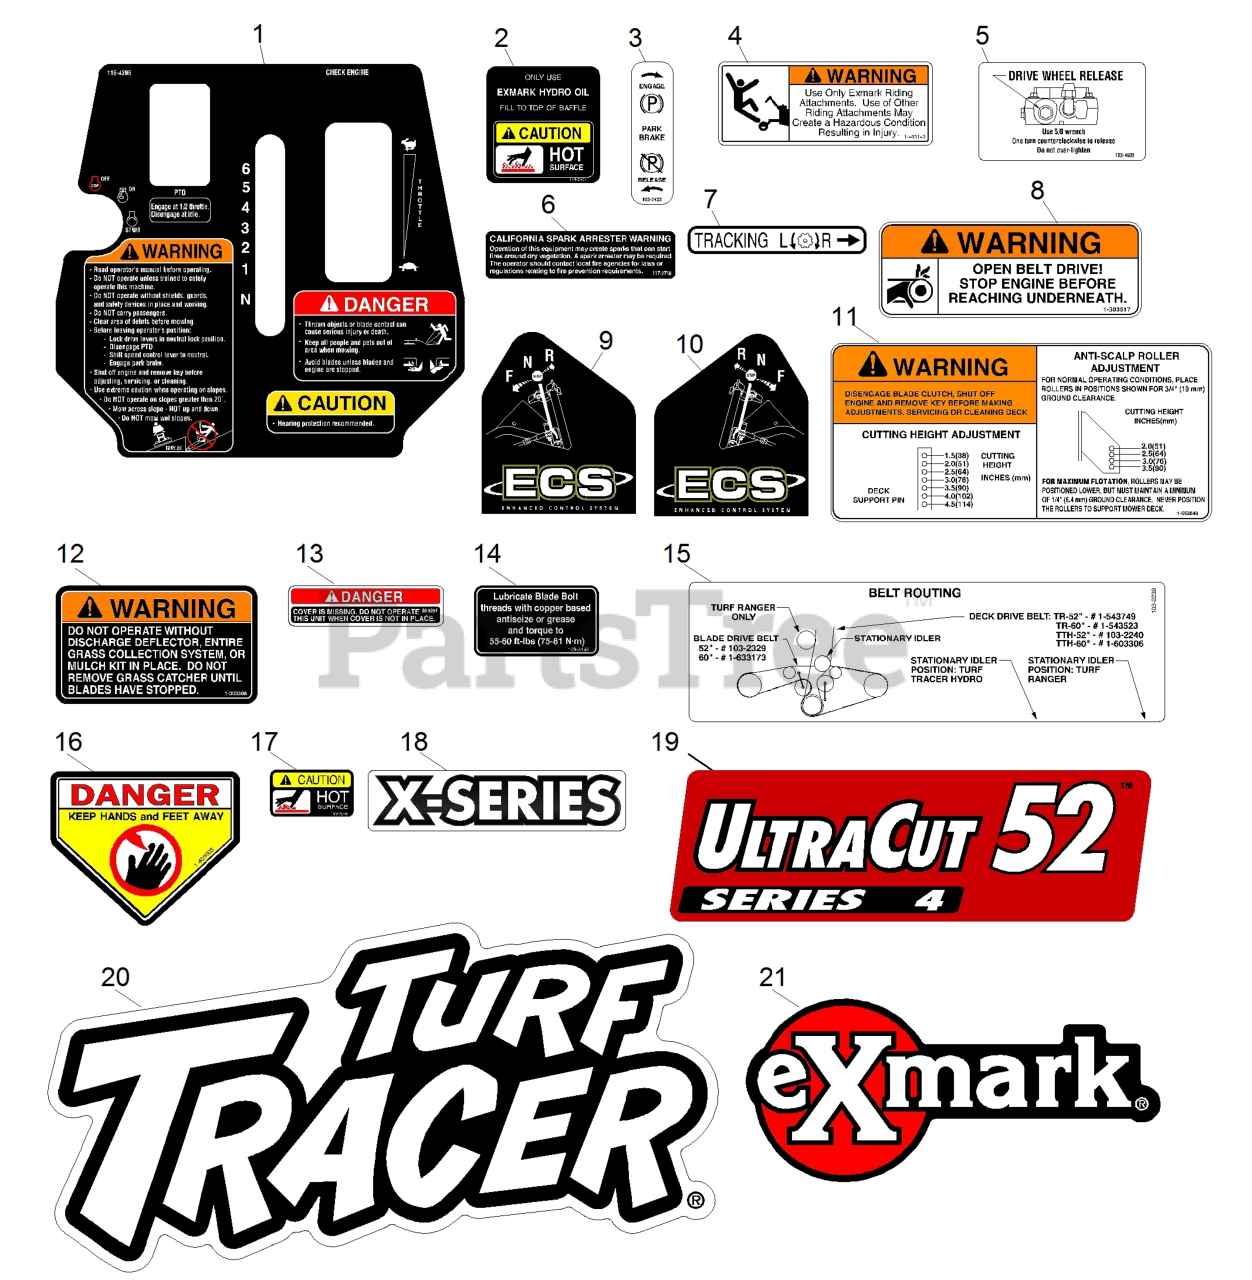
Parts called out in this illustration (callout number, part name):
1	DECAL,CONSOLE TTX
2	DECAL-HYDRAULIC TANK
3	DECAL,PARKING BRAKE
4	DECAL,SULKY WARNING
5	DECAL,DRIVE RELEASE
6	DECAL-ARRESTER, SPARK
7	DECAL,TRACKING ADJUST
8	DECAL,BELT DRIVE
9	DECAL,LH ECS INSTRUCTION
10	DECAL,RH ECS INSTRUCTION
11	DECAL,ANTI SCALP
12	DECAL-WARNING, DISCHARGE
13	DECAL-COVER, MISSING
14	DECAL,BOLT TORQUE
15	DECAL,BELT ROUTING
16	DECAL-DANGER
17	DECAL-CAUTION
18	DECAL-X-SERIES
19	DECAL,ULTRACUT 52 SERIES
20	DECAL,TTH MODEL
21	DECAL,EXMARK LOGO
